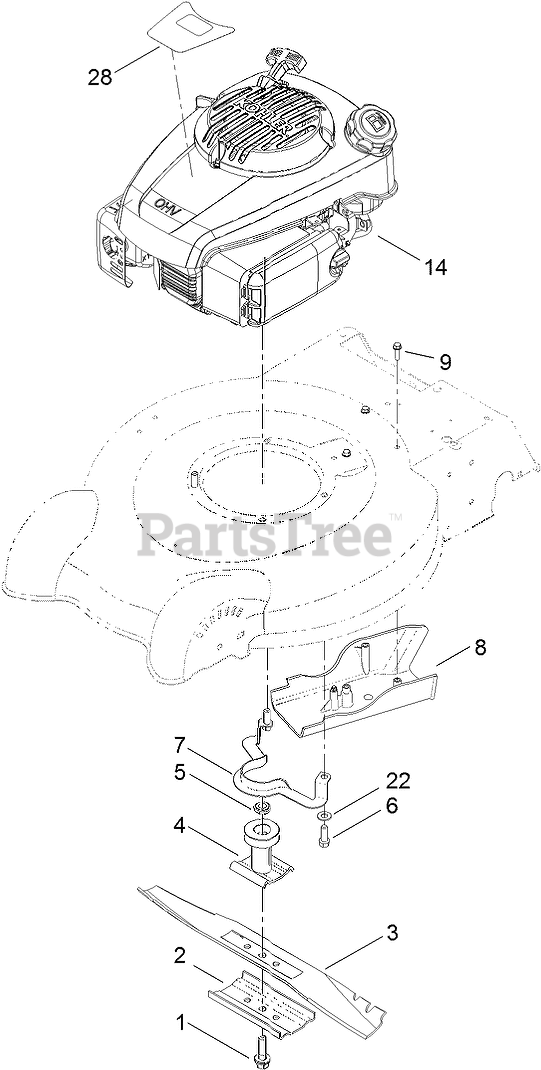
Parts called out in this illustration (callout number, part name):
1	BOLT-BLADE
2	SUPPORT-BLADE
3	BLADE-20 INCH
4	DRIVER-BLADE
5	Spacer-Driver
6	SCREW-TAPTITE
7	Guide-Belt
8	COVER-BELT
9	SCREW-HWH
22	WASHER-FLAT
28	DECAL-SHROUD
